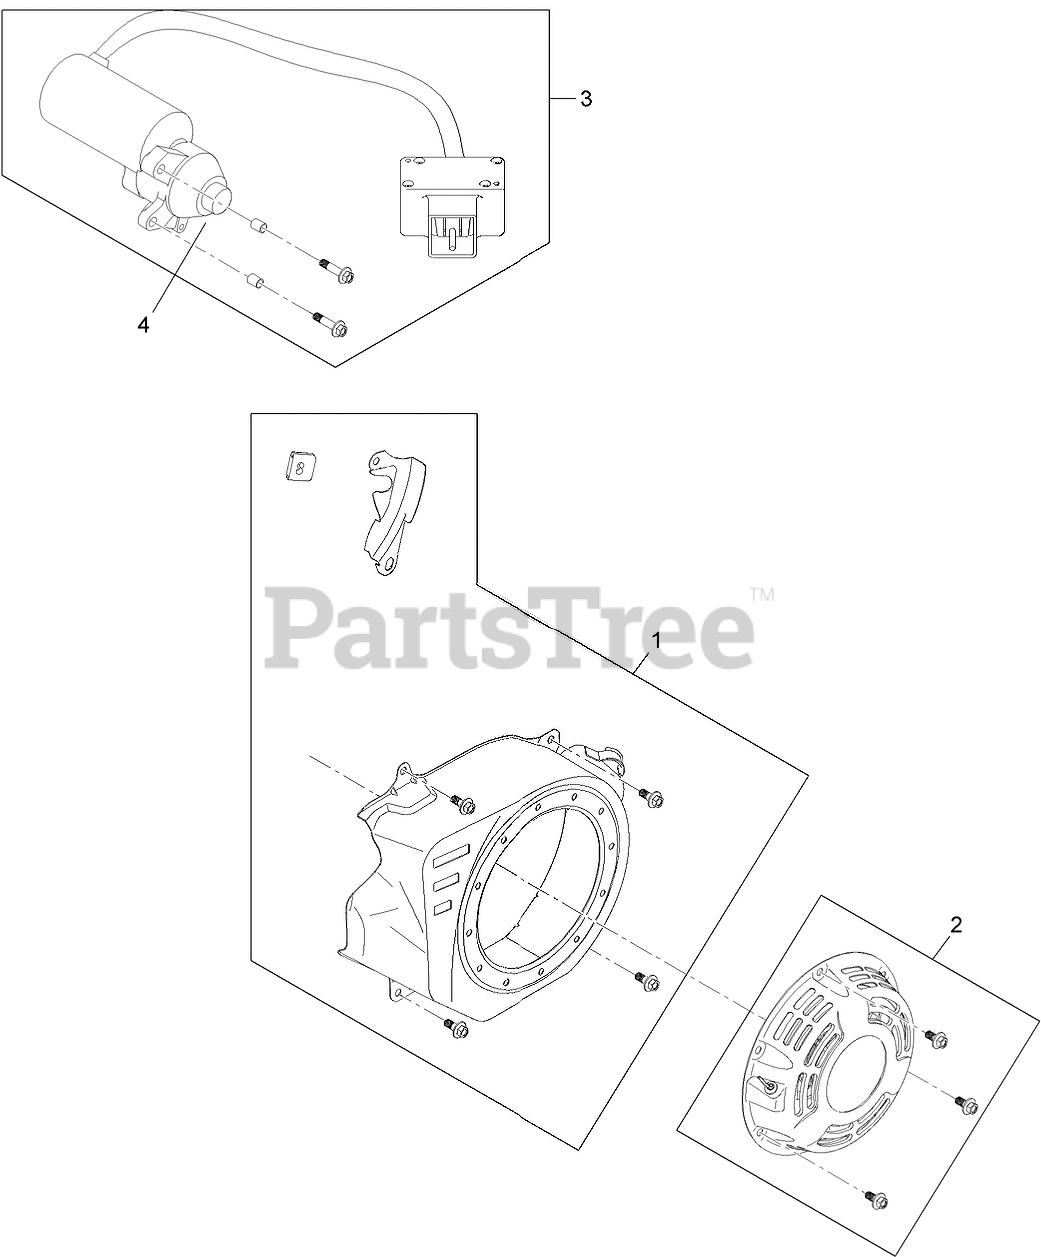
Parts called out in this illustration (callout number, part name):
1	BLOWER SHROUD KIT
2	RECOIL KIT
3	ELECTRIC STARTER KIT
4	PINION KIT
